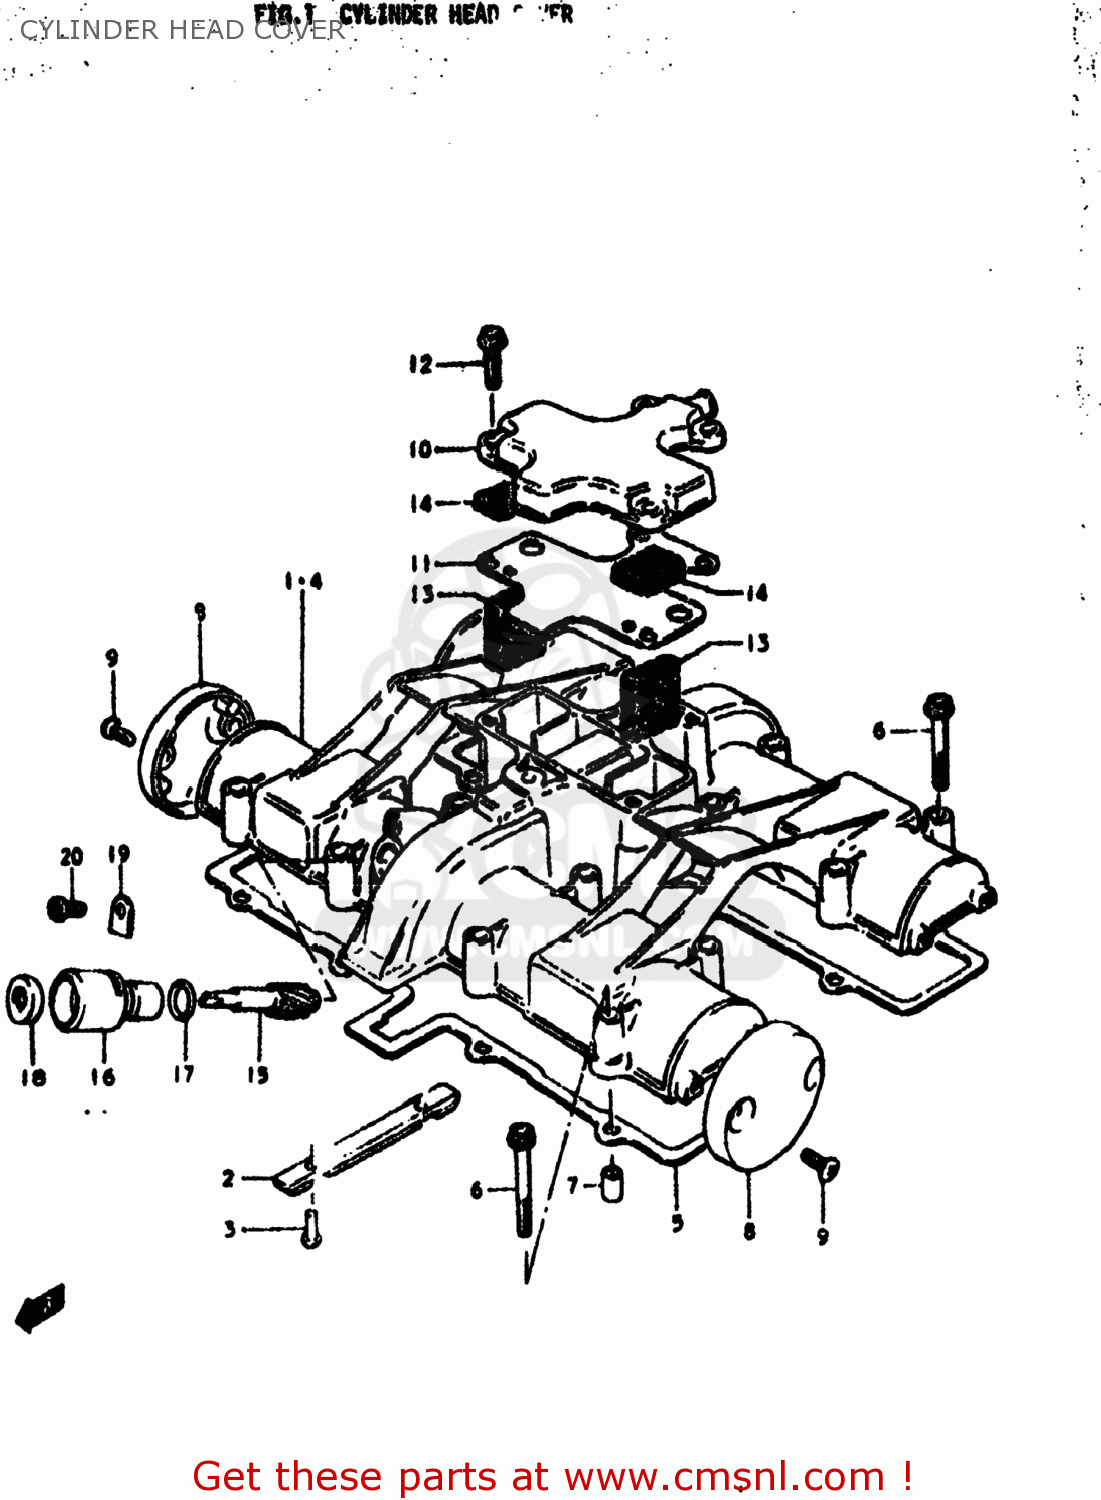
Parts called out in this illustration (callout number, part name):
1	HEAD ASSEMBLY,CYLINDER
2	GUIDE,CAM CHAIN NO.3
3	SCREW
4	COVER,CYLINDER HEAD
5	GASKET,CYLINDER HEAD COVER (MCA)
6	BOLT
7	PIN(6.4X9X10)
8	CAP,CYLINDER HEAD COVER
9	SCREW
10	COVER,BREATHER
11	GASKET (MCA)
12	BOLT,REAR
13	COVER,BREATHER
14	SEPARATOR,OIL BREATHER
15	GEAR,TACHOMETER DRIVEN
16	SLEEVE,TACHOMETER DRIVE
17	SEAL,TACHOMETER DRIVEN
18	SEAL
19	PLATE,TACH DRIVE GEAR SLEEVE
20	SCREW(5X12)
